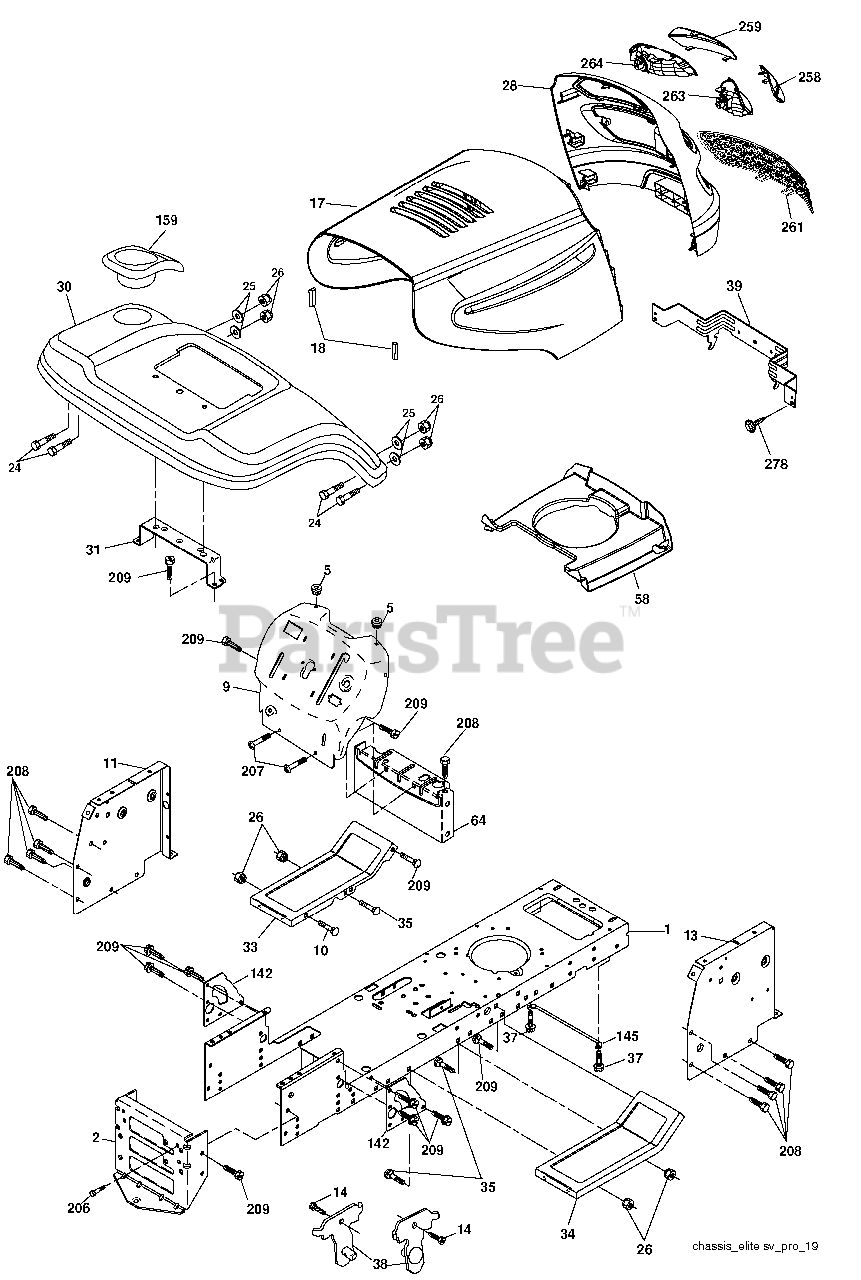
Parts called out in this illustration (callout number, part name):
2	Drawbar
5	Dash
14	Hood
15	Lens Grille LH
18	Grille
25	Lens Grille RH
68	Screw THDROL 5/16-18 x 1/2
99	Rod Bypass Asm
130	Screw 10 x 3/4 Single Lead-Hex
137	Bumper Hood
138	Cupholder
150	Duct Heat Hood
151	Bracket Pivot
152	Shield Browning/Debris
159	Screw Hexwsh Thdrol 3/8-16 x 3/4
162	Screw Hex Wsh Hi-Lo 1/4 x 1/2 UNC
175	Crossmember
176	Screw 10-24 x 5/8 Wshd Qdrx
177	Bushing Steering
181	Bushing Mtg. Fender Crgo.
182	Dash Lower
183	Bolt Fin Hex 5/16-18 x 1-1/4
184	Spacer Fender
189	Screw 5/16-18 x 3/4
194	Nut Lock Hex Flange 5/16-18
196	Console Asm. Deck Lift
197	Rod Pivot Chassis
207	Bezel RH
208	Bezel LH
219	Stud Fastener
222	Screw thd Roll 1/4-20 x 5/8
229	Screw 3/8-16 x 1
230	Bolt Shoulder 5/16-18
230	Plug Cruise/Hook/Phone
